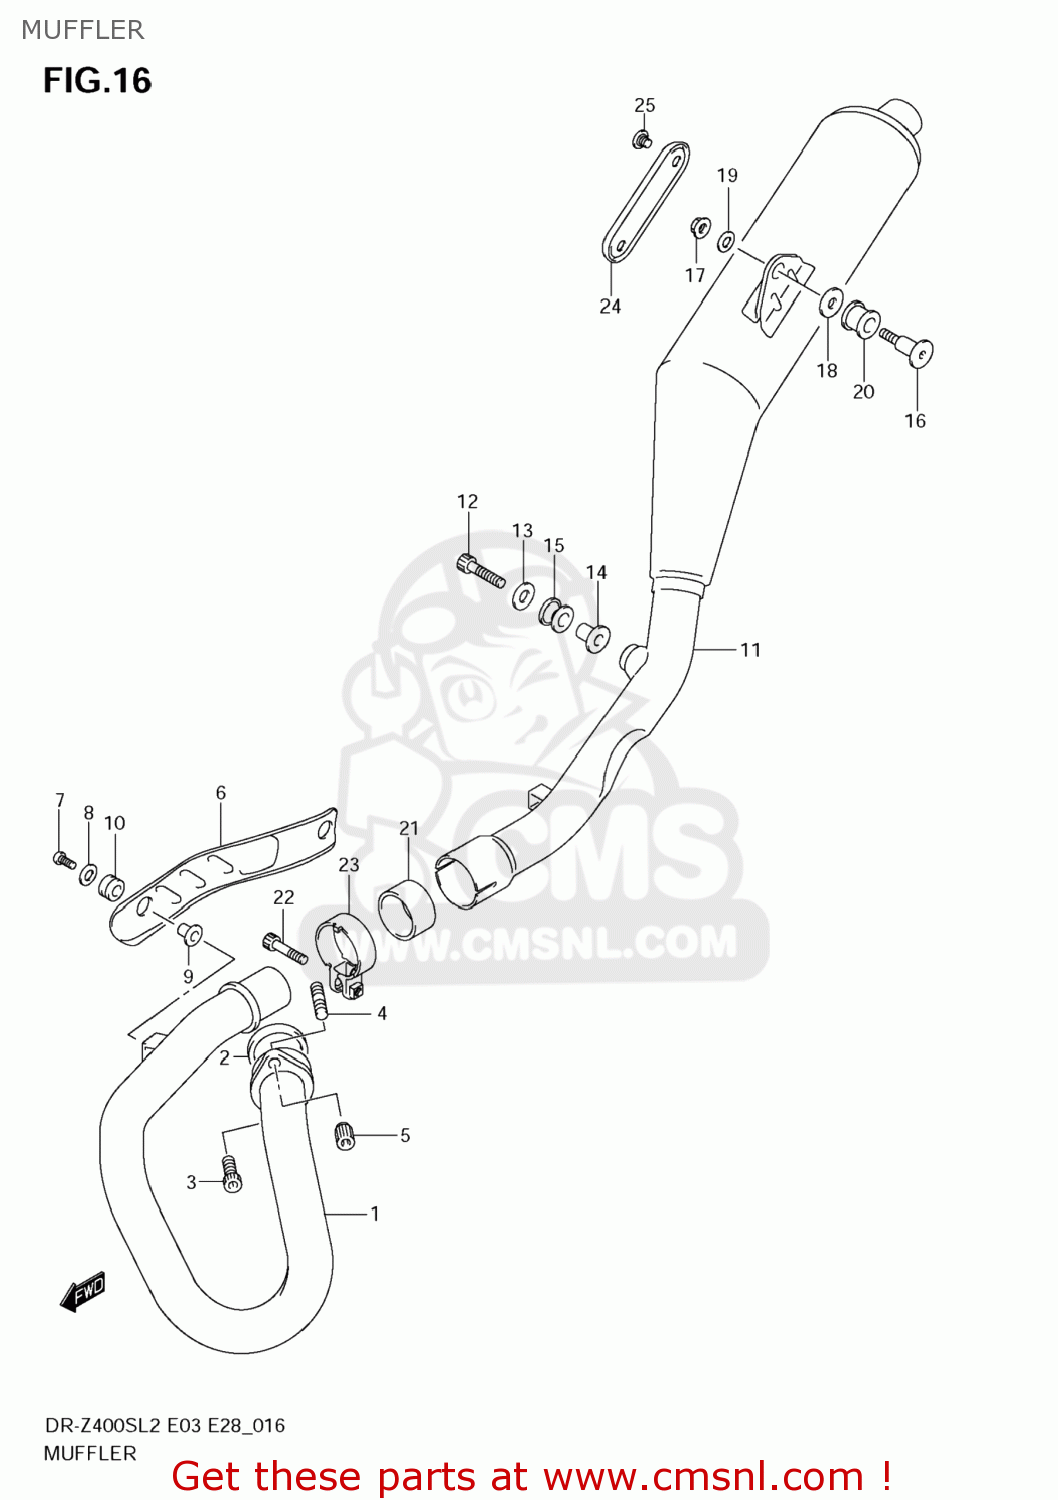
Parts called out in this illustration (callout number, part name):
1	PIPE,EXHAUST
2	GASKET,EXHAUST PIPE
3	BOLT
4	BOLT,STUD
5	NUT
6	COVER,EXHAUST PIPE
7	SCREW(6X16)
8	WASHER(6.5X18X1)
9	SPACER,EXHAUST PIPE COVER
10	CUSHION
11	BODY,MUFFLER
12	BOLT(8X35)
13	WASHER(8.5X26X1.6)
14	SPACER(8.6X12X17.5)
15	CUSHION
16	BOLT,MUF SPRT RR
17	NUT
18	WASHER(8.5X30X2.3)
19	WASHER
20	CUSHION
21	CONNECTOR,MUFFLER JOINT
22	BOLT
23	CLAMP,MUFFLER CONNECTOR
24	COVER,MUFFLER
25	SCREW
